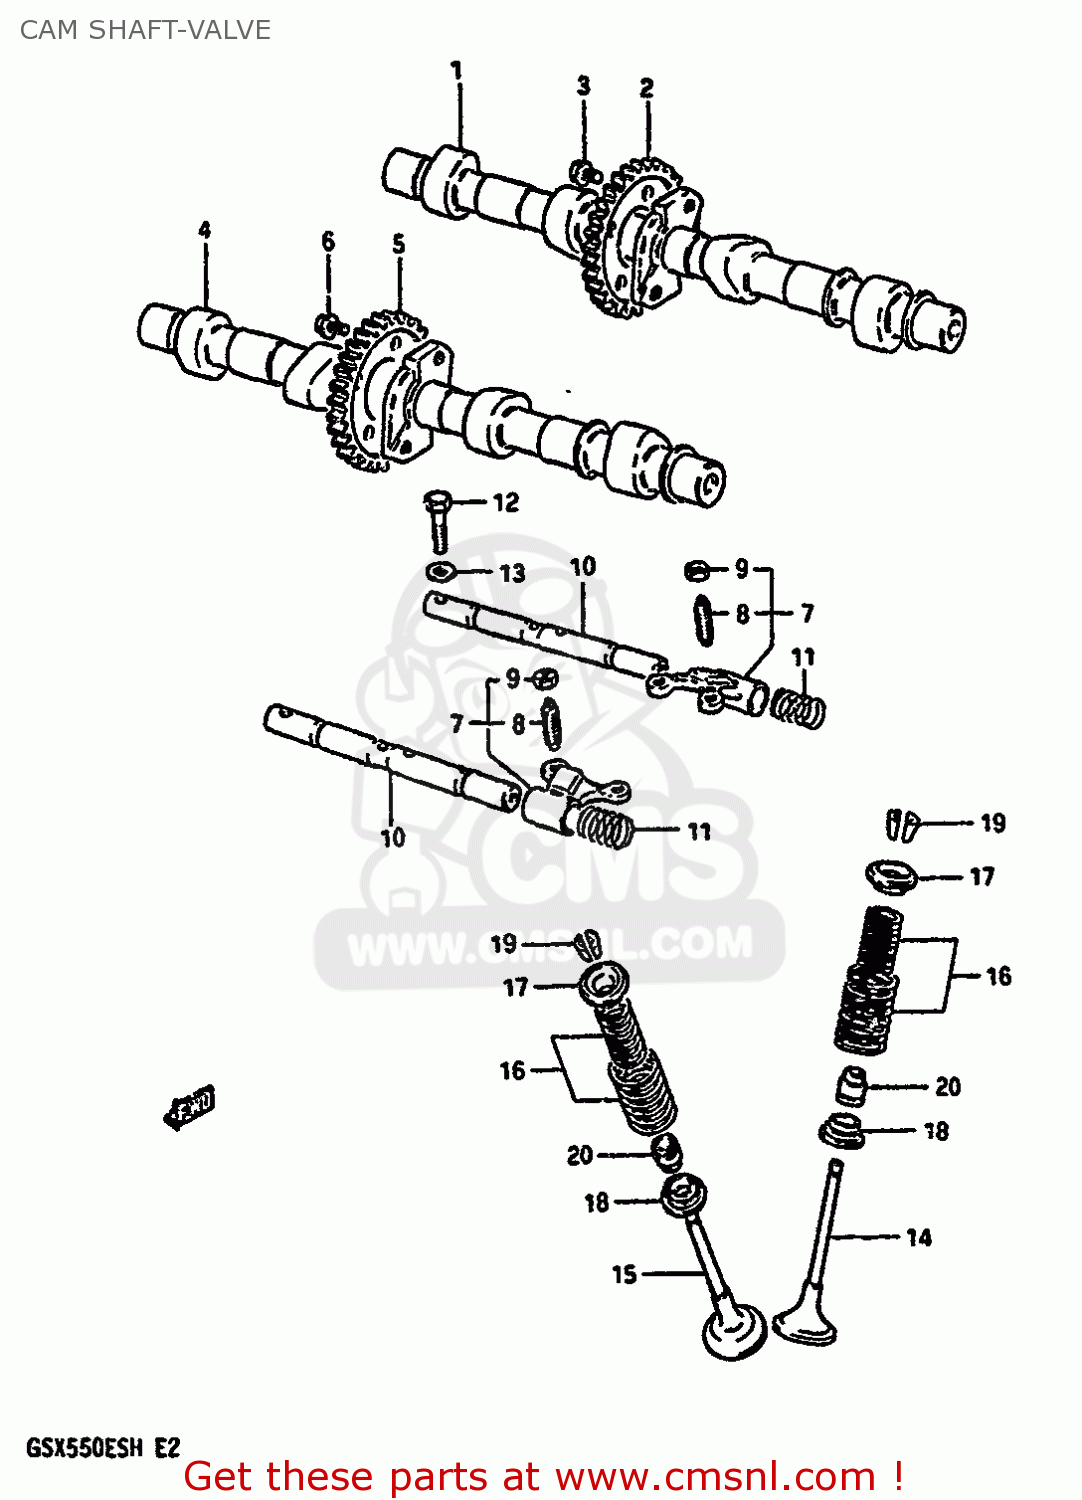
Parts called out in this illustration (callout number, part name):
1	CAMSHAFT,INTAKE
2	SPROCKET,INTAKE CAMSHAFT
3	BOLT(7X11)
4	CAMSHAFT,EXHAUST
5	SPROCKET,INTAKE CAMSHAFT
6	BOLT(7X11)
7	ARM,VALVE ROCKER
8	SCREW,TAPPET ADJUSTING
9	NUT,ADJUSTING
10	SHAFT,VALVE ROCKER
11	SPRING
12	BOLT
13	WASHER, LOWER
14	VALVE,INTAKE
15	VALVE,EXHAUST
16	SPRING SET,VALVE
17	RETAINER,VALVE SPRING
18	SEAT,VALVE SPRING
19	COTTER VALVE
20	SEAL,OIL(5X10.5X8.4)
